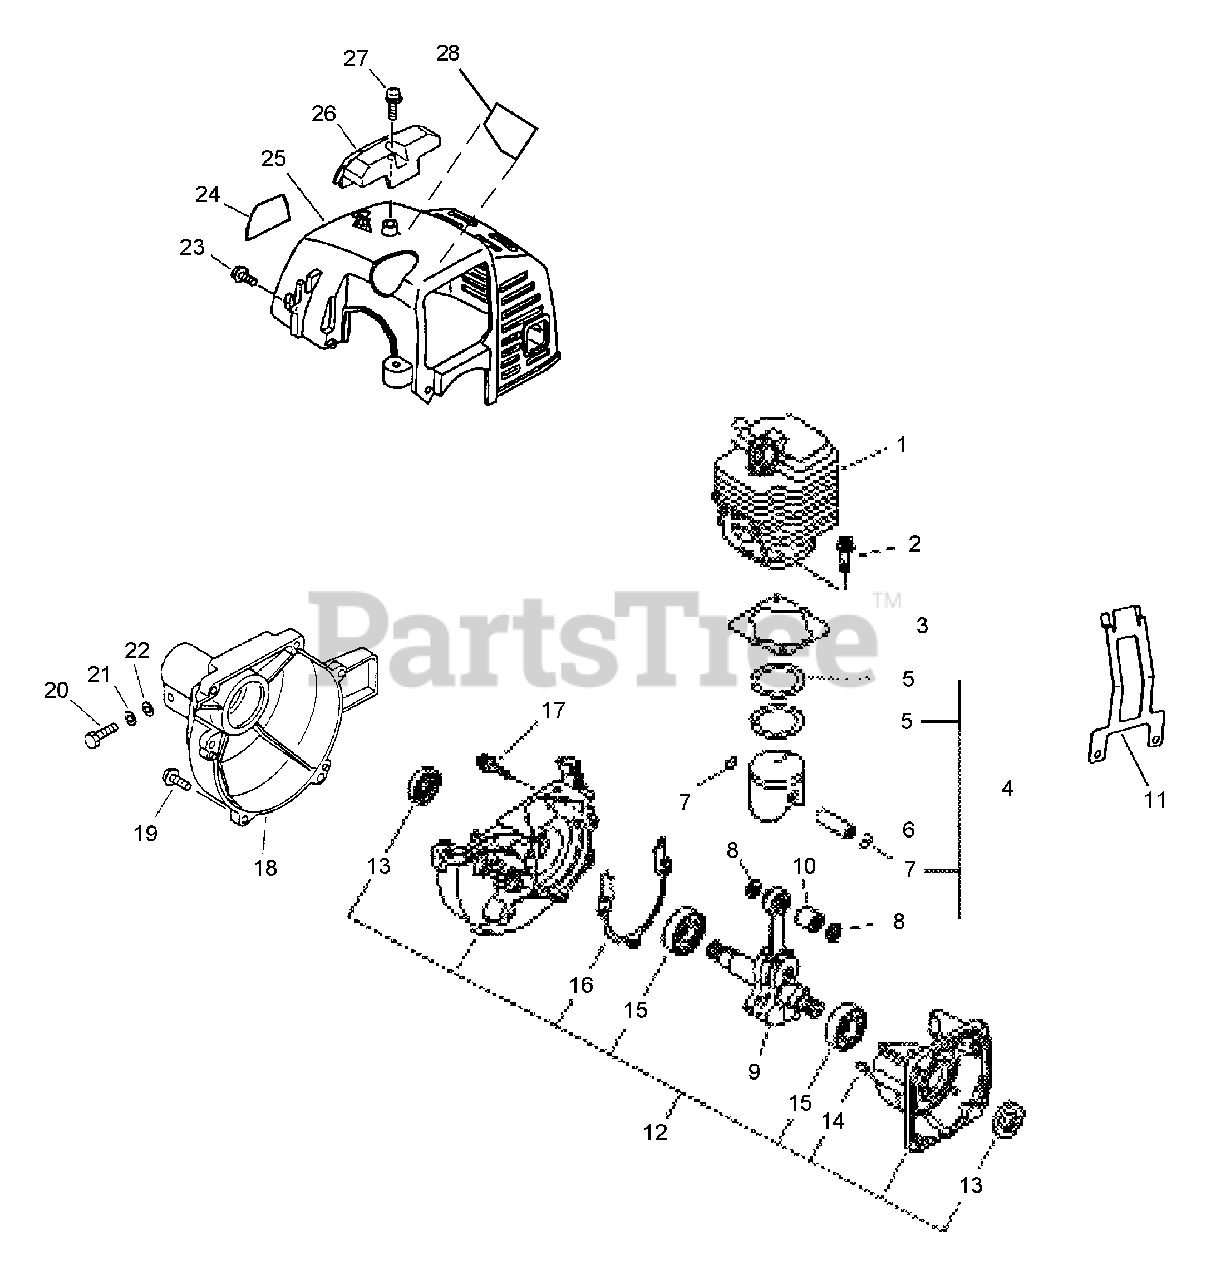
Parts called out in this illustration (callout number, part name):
1	CYLINDER
2	SCREW - 5X22
3	GASKET, CYLINDER
4	PISTON KIT
5	RING, PISTON
6	PIN, PISTON
7	RING, RETAINING
8	SPACER, PISTON
9	CRANKSHAFT ASSY
10	BEARING, NEEDLE
11	GUARD, ENGINE
12	CRANKCASE ASSY
13	SEAL, OIL
14	PIN - LOCATING
15	BEARING, BALL - 6201
16	GASKET, CRANKCASE
17	SCREW - 5X28
18	CASE, FAN - ORANGE
19	SCREW - 4X16
20	BOLT - 5X25
21	LOCKWASHER - 5
22	WASHER - 5
23	SCREW - 4X12
24	LABEL - MODEL PPF-2100
25	COVER, ENGINE - ORANGE
26	GUARD, TOP - BLACK
27	SCREW - 5X16 -- TAPPING
28	LABEL - CAUTION
